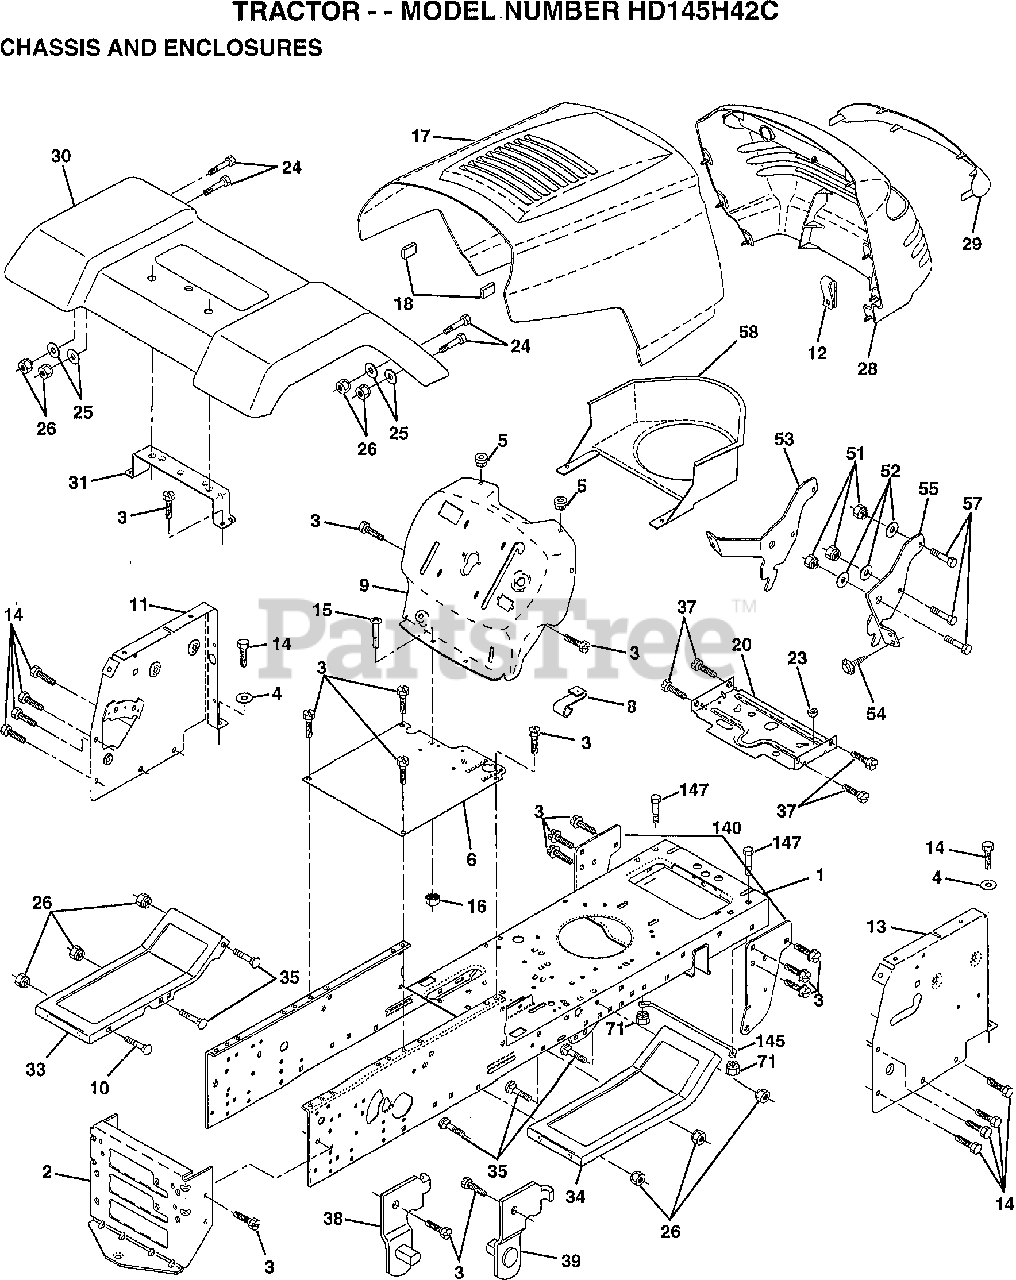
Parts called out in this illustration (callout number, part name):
1	CHASSIS ASM
3	SCREW
4	WASHER
5	BUMPER-HOOD/DASH
6	SADDLE
8	CLIP.RETAINER
9	DASH.SILKSCREENED
11	"PANEL-DASH,LH"
12	CLIP.TINNERMAN
14	SCREW LT
15	SCREW
20	"PLATE-MTG,BATT/FU"
24	BOLT
25	WASHER
26	NUT
28	GRILLE-MS428
29	LENS GRILLE
30	FENDER ASM LT W/S
31	BRKT FENDER
33	FOOTREST LH
34	FOOTREST RH
35	BOLT
37	SCREW LT
38	BRACKET ASM LH
39	BRACKET ASM RH
51	NUT
52	WASHER
53	BRACKET.GRILLE.LH
55	BRACKET.GRILLE.RH
58	AIR DUCT
140	BRKT SUSPENSION
145	"ROD POVOT,CHASSIS"
147	BOLT LT
